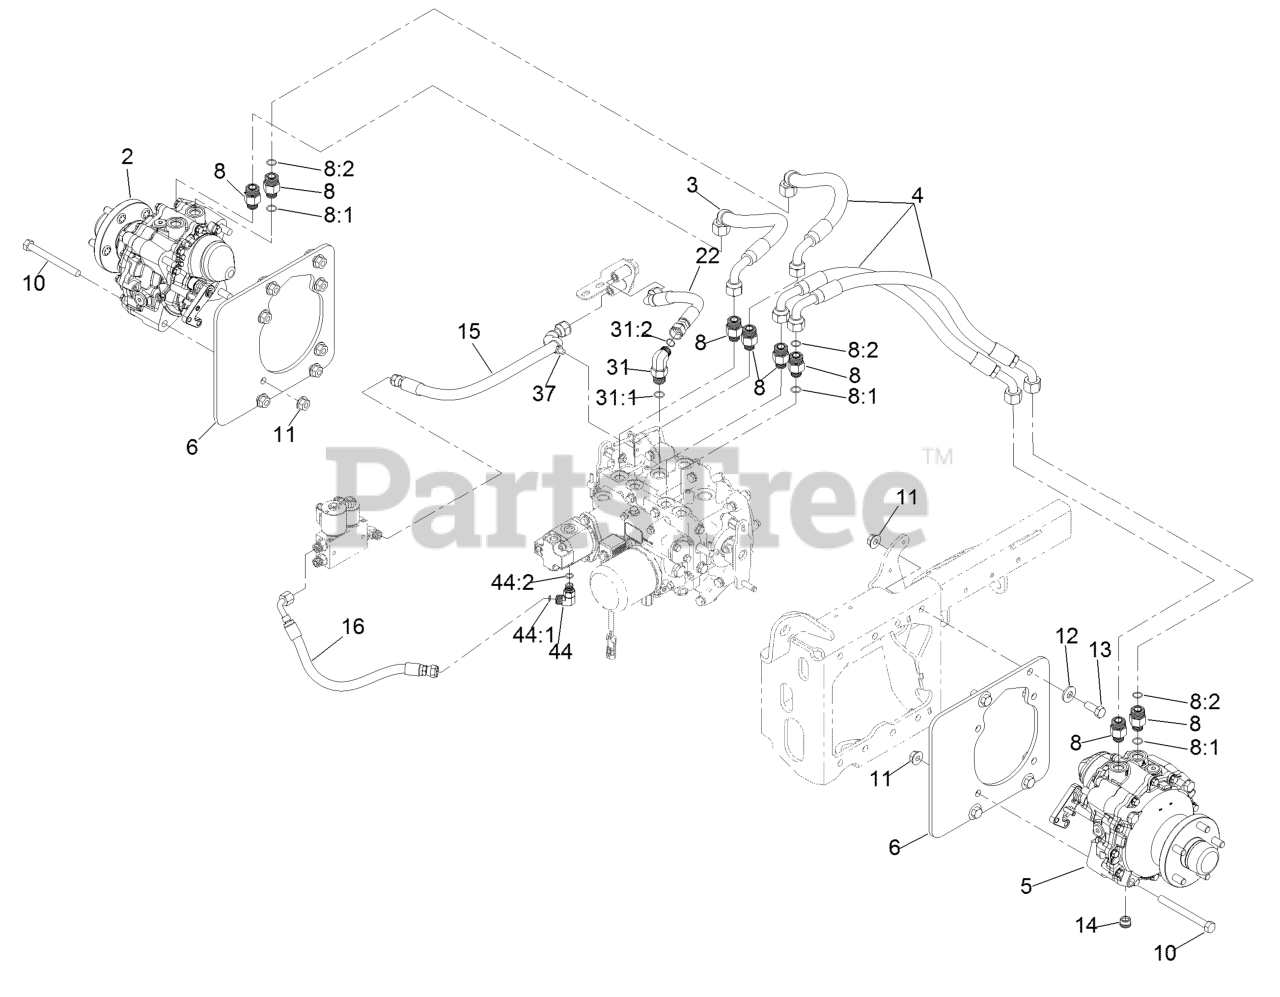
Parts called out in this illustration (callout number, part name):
2	Motor-HYD, RH
3	Hose ASM
4	Hose ASM
5	Motor-HYD, LH
6	Plate-Motor
8	Fitting-Straight
8:1	O-Ring
10	Screw-HH 1/2-13 X 5
11	Nut-Whizlock 1/2-13
12	Washer-Spring Disc 1/2
13	Screw-HH 1/2-13 X 1 1/4
14	Plug-Magnetic
15	Hose ASM
16	Hose ASM
22	Hose ASM
31	Fitting-Elbow, 90 DEG
31:1	O-Ring
31:2	O-Ring
37	Clip-Tie
44	Fitting-Elbow, 90 DEG
44:1	O-Ring
44:2	O-Ring
